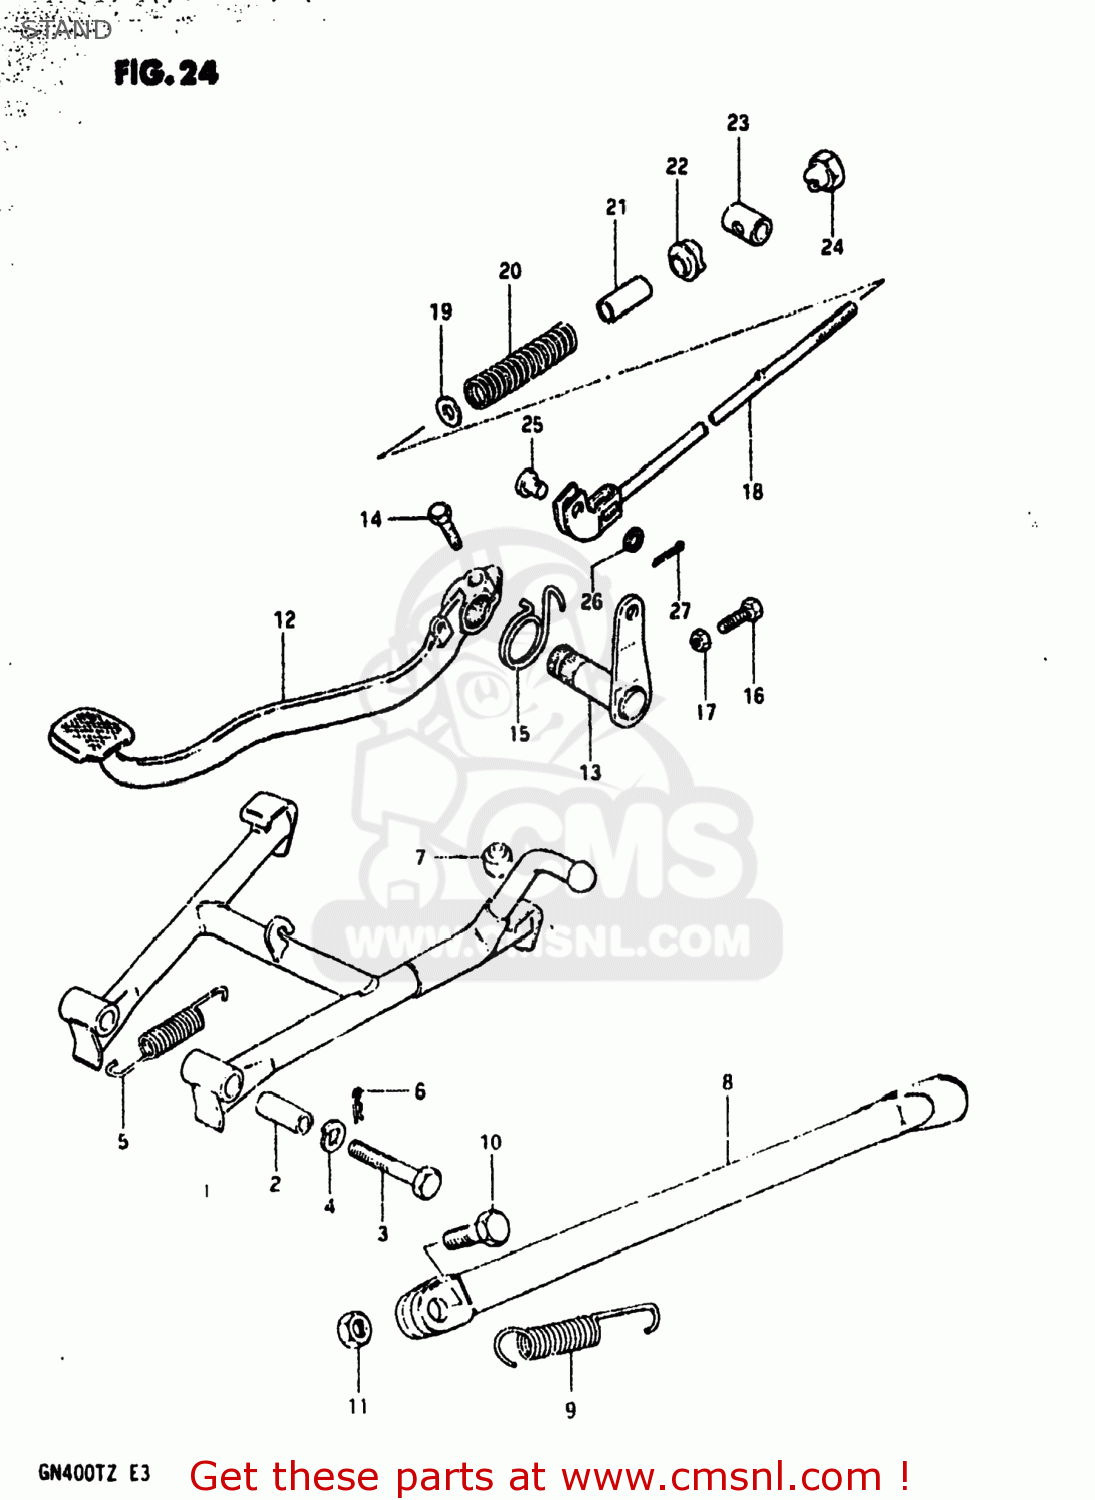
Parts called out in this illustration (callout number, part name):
1	STAND,CENTER
2	SPACER(10X16X38.8)
3	BOLT
4	LOCK WASHER
5	SPRING
6	CLIP
7	CUSHION
8	STAND,SIDE
9	SPRING
10	BOLT(10X30)
11	NUT
12	PEDAL,BRAKE
13	ARM,BRAKE PEDAL
14	BOLT
15	SPRING
16	BOLT(6X23)
17	NUT
18	ROD ASSEMBLY,REAR BRAKE
19	WASHER
20	SPRING
21	CUSHION,FR GRILLE,UPPER
22	CUSHION
23	PIN
24	NUT
25	PIN,REAR BRAKE ROD
26	WASHER
27	COTTER PIN
